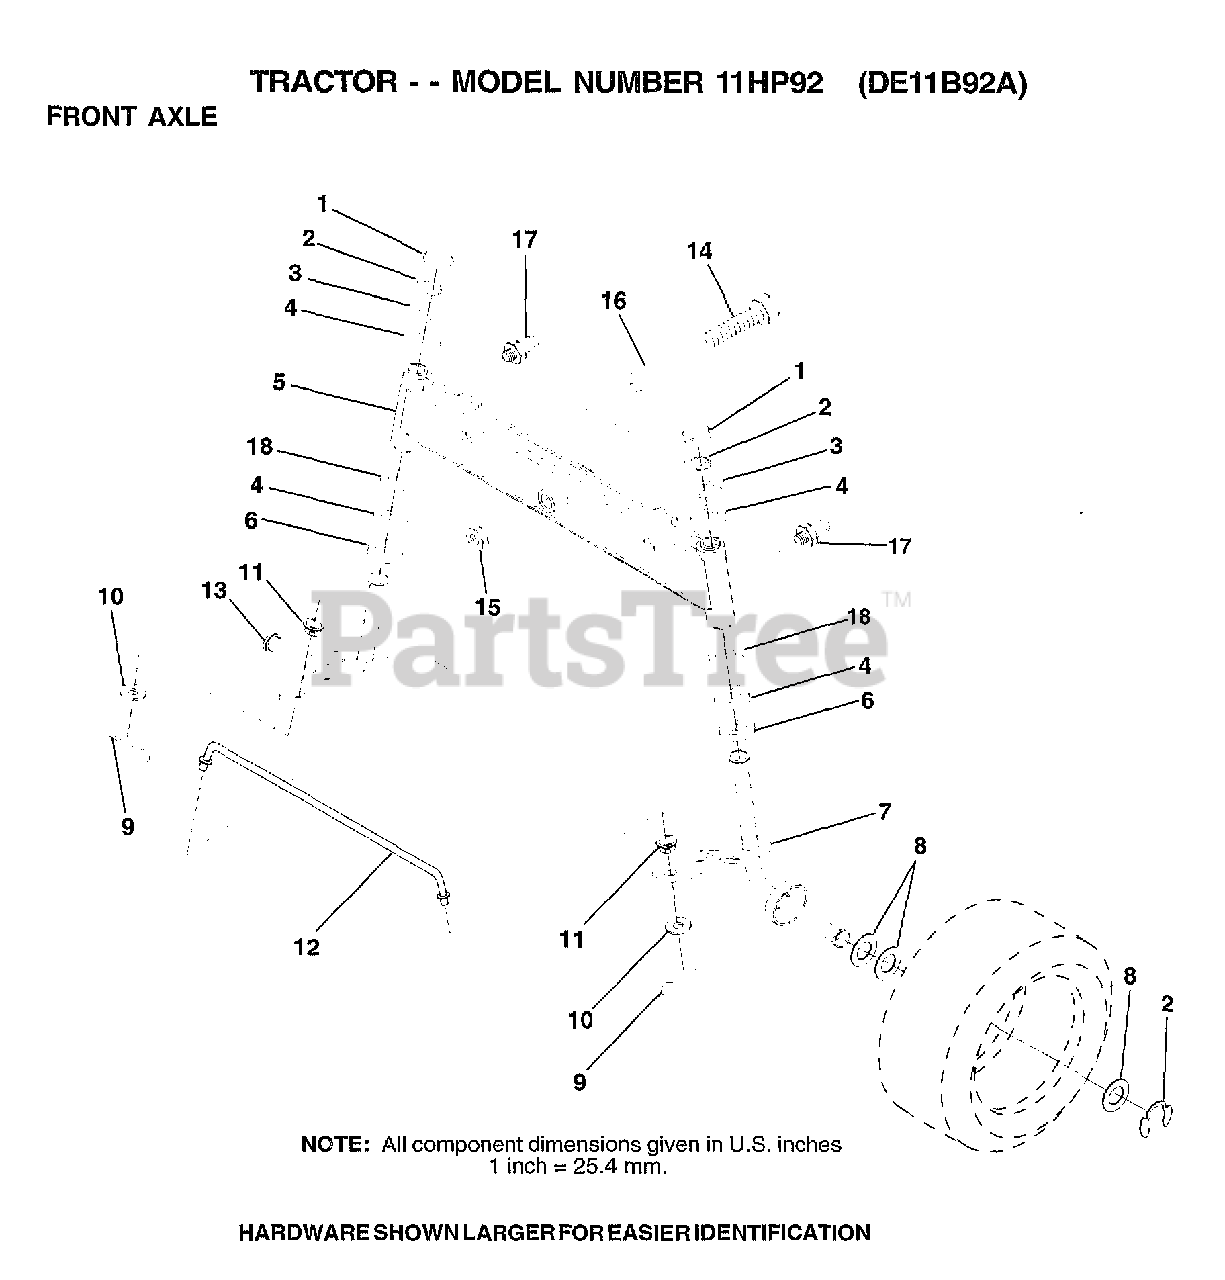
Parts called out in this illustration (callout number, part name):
1	CAP
2	RING
3	WASHER
4	COL. SRTG. BEAR.
5	AXLE ASM FRONT
6	WASHER .T
7	SPINDLE.ASSY.RH
8	WASHER
9	COTTER PIN
10	WASHER
11	BUSHING.DRAGLINK
12	TIE ROD
13	SPINDLE.ASSY.LH
14	BOLT HEX 5/8-11
15	"NUT-LOC,FLANGE LT"
16	BEARING
17	ZERK M
18	WASHER
